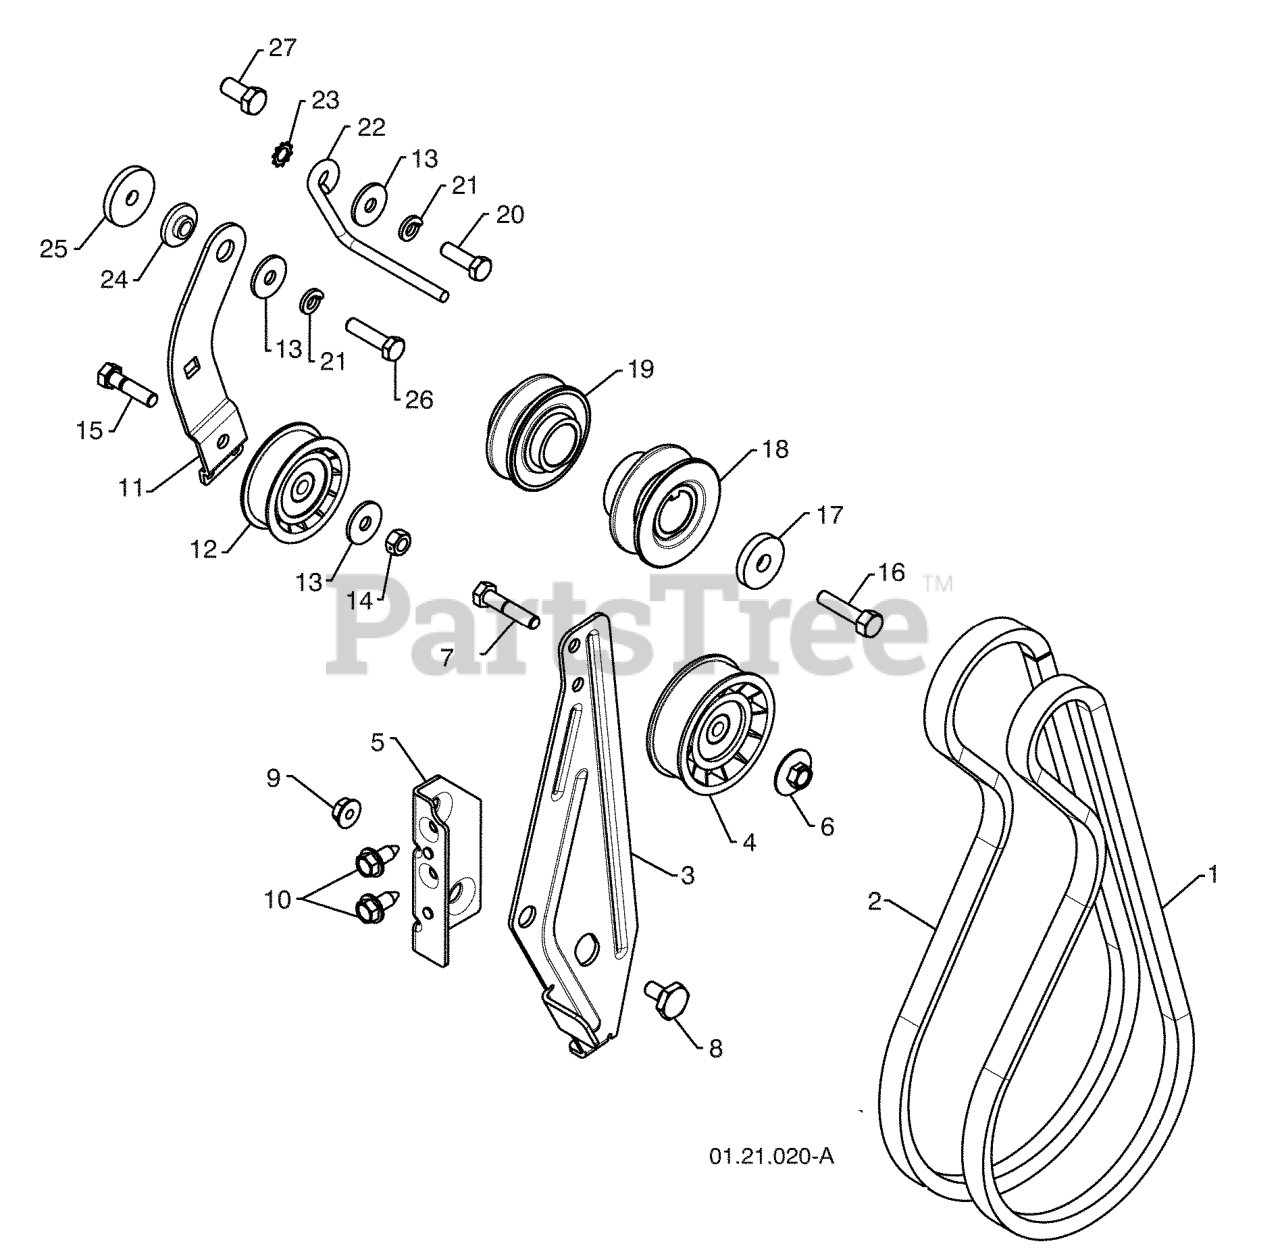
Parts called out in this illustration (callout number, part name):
1	V-BELT.IMPELLER
2	TRACTION BELT
3	ARM.IDLER.BRAKE.PNT.BLACK
4	PULLEY.W/SPACER.2.75
5	RP.BRACKET.IDLER.PIVOT.BLACK
6	NUT.FLANGE.HEX.5/16X18.BLACK
7	HEX BOLT
8	BOLT.SHOULDER.1/2X12
9	NUT.LOCK.5/16-18
10	BOLT.HEX.HD.WASHER.5/16-18X.75
11	RP ARM.ASM.TRACTION.IDLER
12	PULLEY.W/SPACER.2.25
13	STEEL WASHER
14	NUT.71038.31-18.HEX.NYLOCK
15	BOLT.5/16-18X1-1/4 FULL.THREAD
16	SCREW, HEX HD 3/8-24 X 1-3/8
17	WASHER.400X1.25X5.
18	PULLEY ENG IMPELLER
19	PULLEY.ASM.ENG.TRACTION.1.00
21	WASHER.LOCK.HVY.HLCL.SPR.5/16
22	BELT.GUIDE.RH
23	WASHER EXT TOOTH LOCK 5/16
24	RP BUSHING, IDLER PIVOT
25	WASHER.FLAT.34X1.38X22
26	CAPSCREW.HEXHD.5/16X1.25.
27	SCREW.3/8-16 X .750 (2 2)
